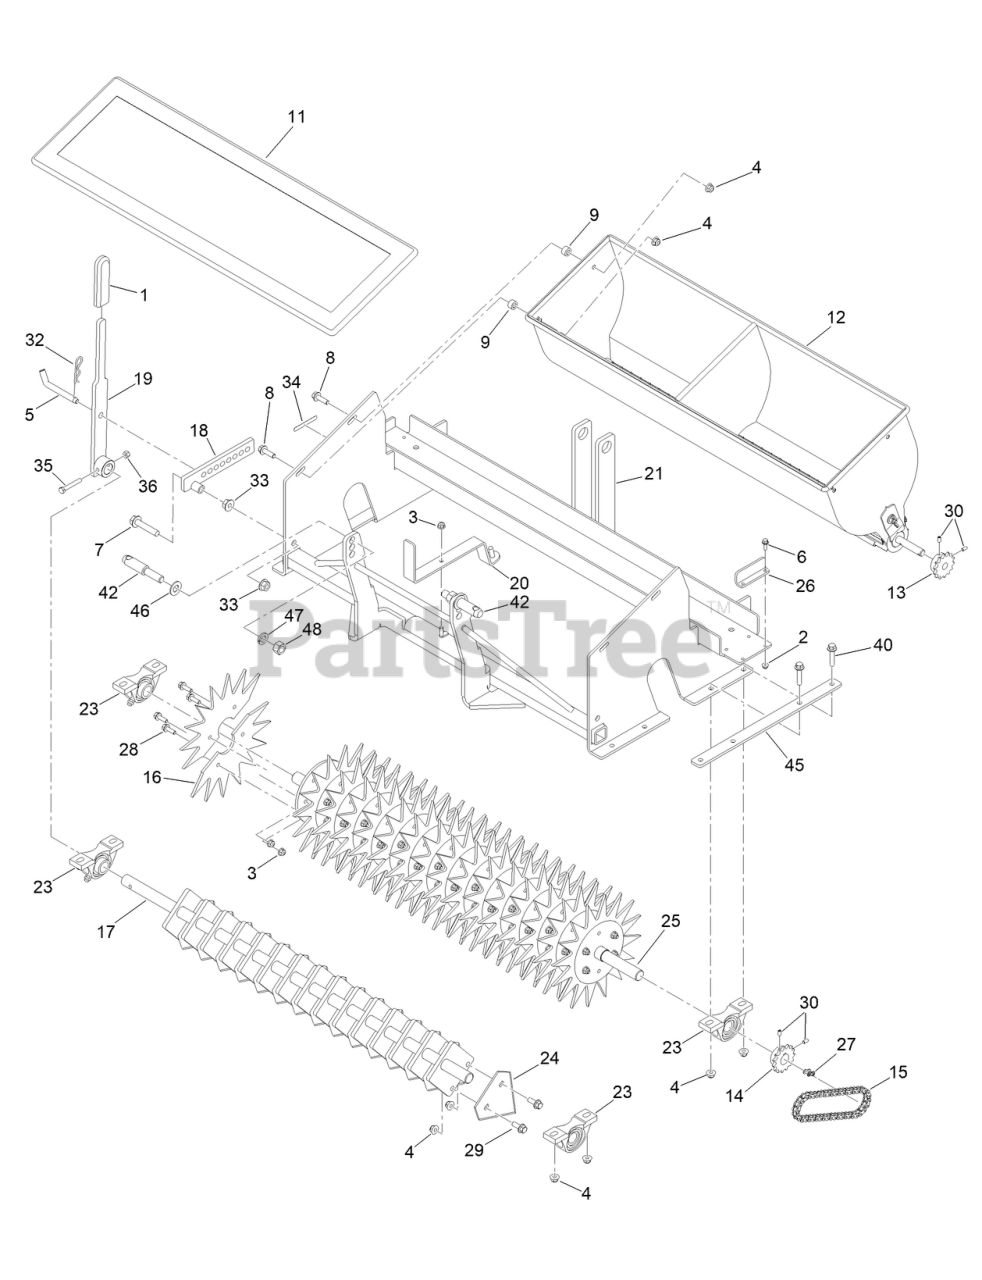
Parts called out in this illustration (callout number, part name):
1	GRIP-LEVER
3	NUT-HF, NI
4	NUT-HF, NI
5	1/2 X 4-3/4 BENT PIN
6	Screw-HHF
7	SCREW-HHF
8	SCREW-HHF
9	BUSHING-HOPPER
11	SLIT SEEDER DROP COVER
12	36" SLIT SEEDER HOPPER
13	SPROCKET-UPPER,SEEDER\NDA
14	SPROCKET-LOWER,SEEDER\NDA
15	Chain-Roller
16	Star, Slit Seeder
17	Shaft-Sq Plate [blk-Txt]
18	ARM-CTRL. SEEDER
19	Handle-Slit Seeder [blk-Txt]
20	Handle-Gate [blk-Txt]
21	FRAME-SEEDER, SLIT
23	PILLOW BLOCK BEARING
24	4' SLICING KNIFE\NR201313
25	DISC-SLIT SEEDER
26	Bracket-Weight [blk-Txt]
27	Link-Chain
28	SCREW-HHF
29	SCREW-HHF 3/8-16 X 1
30	Screw-Set, HSH
32	PIN-HAIR
33	NUT-HHF
34	DECAL-WARNING
35	SCREW-HH
36	NUT-LOCK, NI
40	SCREW-HHF
42	PIN-LIFT
45	PLATE-DOUBLER
46	WASHER-FLAT
47	WASHER-LOCK
48	NUT-HEX
